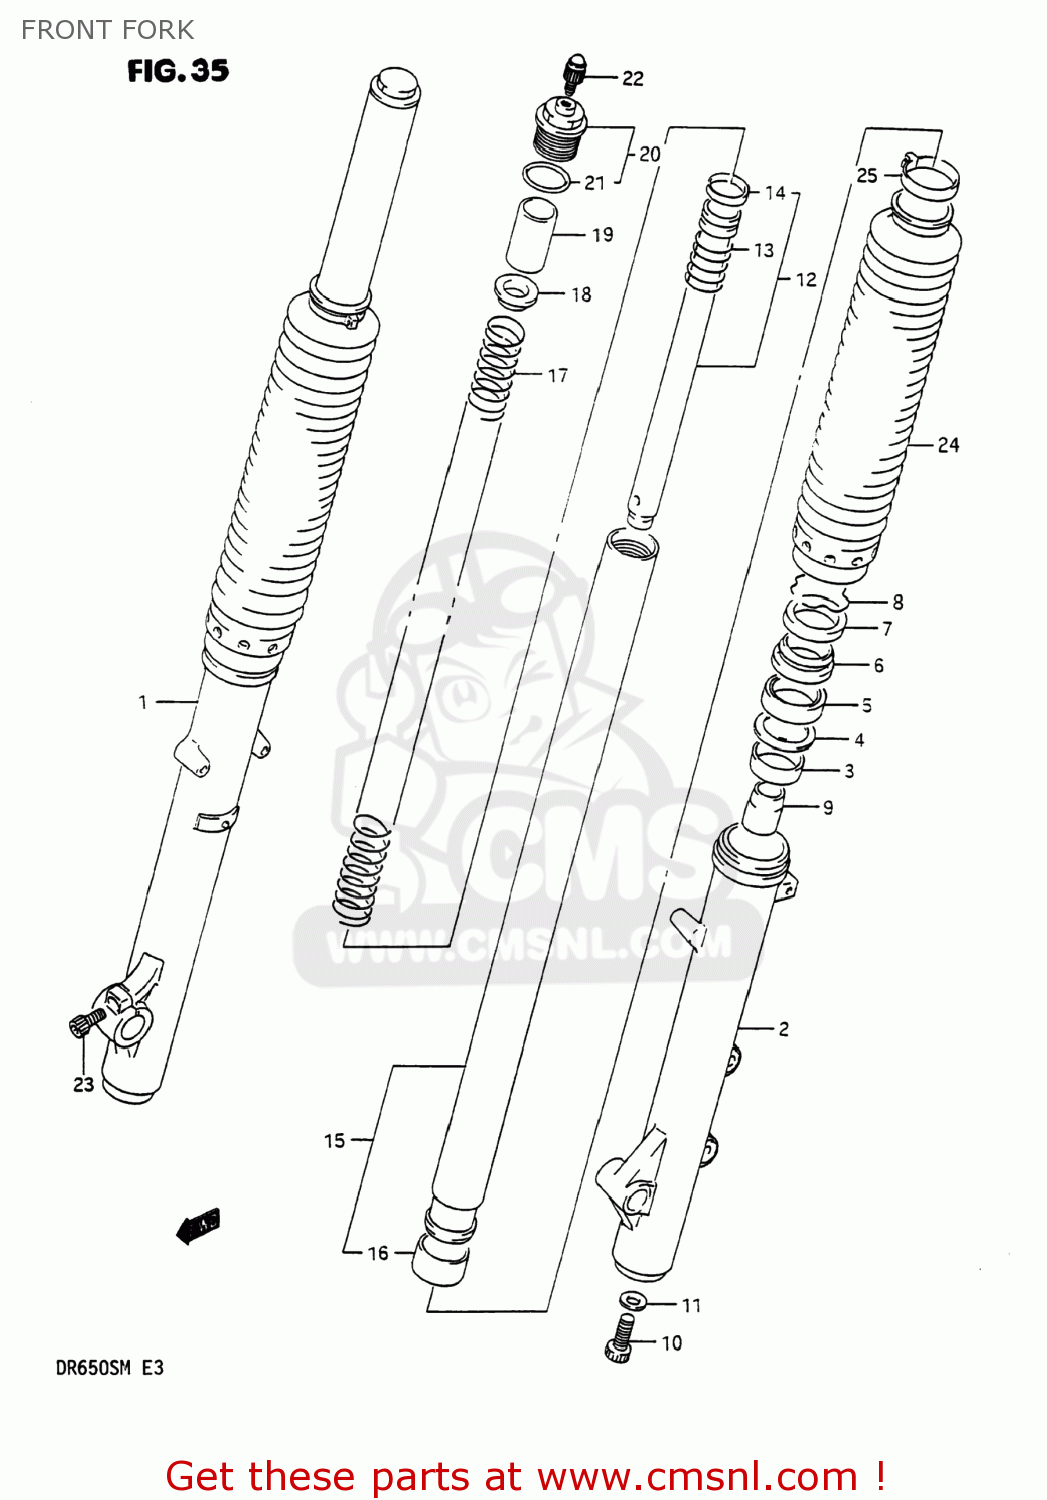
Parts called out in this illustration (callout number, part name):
1	TUBE,OUTER,RIGHT
2	TUBE,OUTER,LEFT
3	METAL,SLIDE
4	WASHER,FORK OIL SEAL
5	SEAL,OIL
6	SEAL,DUST
7	WASHER
8	RING,OIL SEAL STOPPER
9	PIECE,OIL LOCK
10	BOLT(14X25)
11	GASKET (NAS)
12	CYLINDER
13	SPRING,REBOUND
14	RING,FR FORK PISTON
15	TUBE,INNER
16	PISTON
17	SPRING,MAIN
18	GUIDE,SPRING
19	SPACER,SPRING
20	CAP,FORK
21	O-RING
22	CAP
23	BOLT,SOCKET HEAD(8X22)
24	BOOT(BLUE)
25	BAND,BOOT
